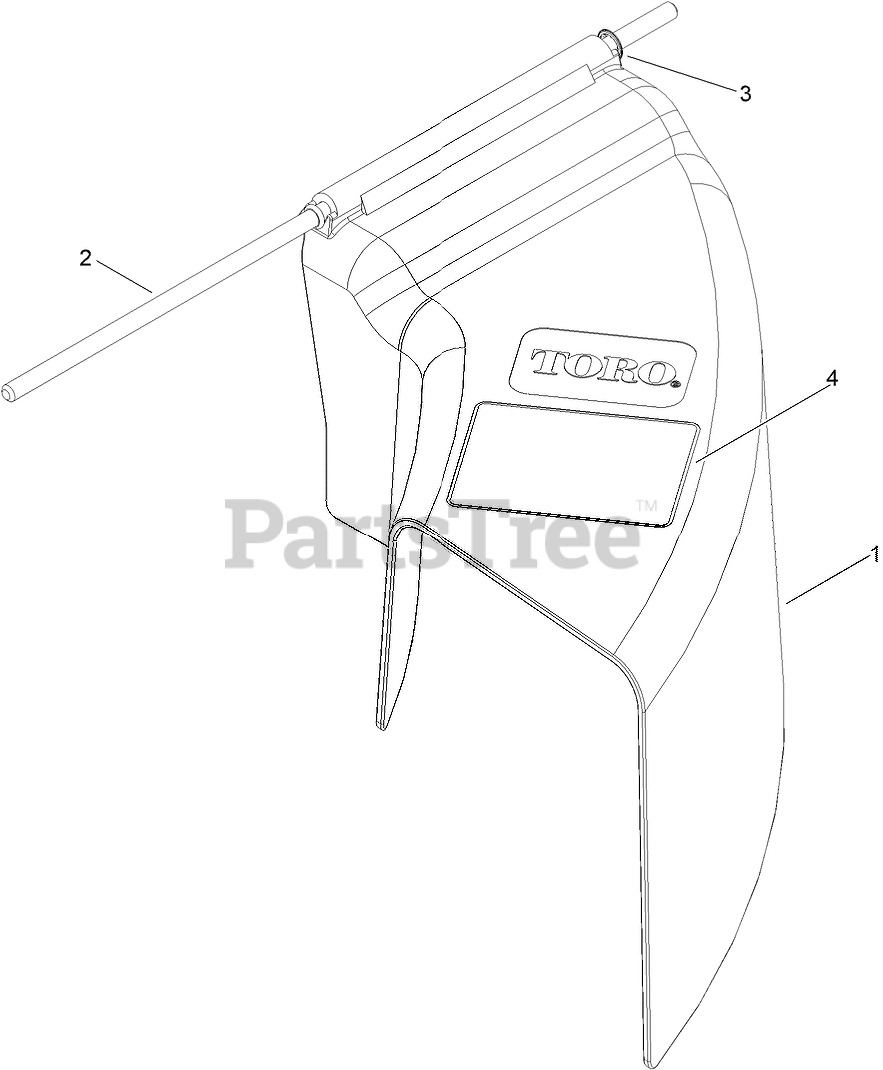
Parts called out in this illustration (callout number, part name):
1	CHUTE-DISCHARGE, SIDE
2	ROD-CHUTE, SD
3	RING-RETAINING
4	DECAL-WARNING
